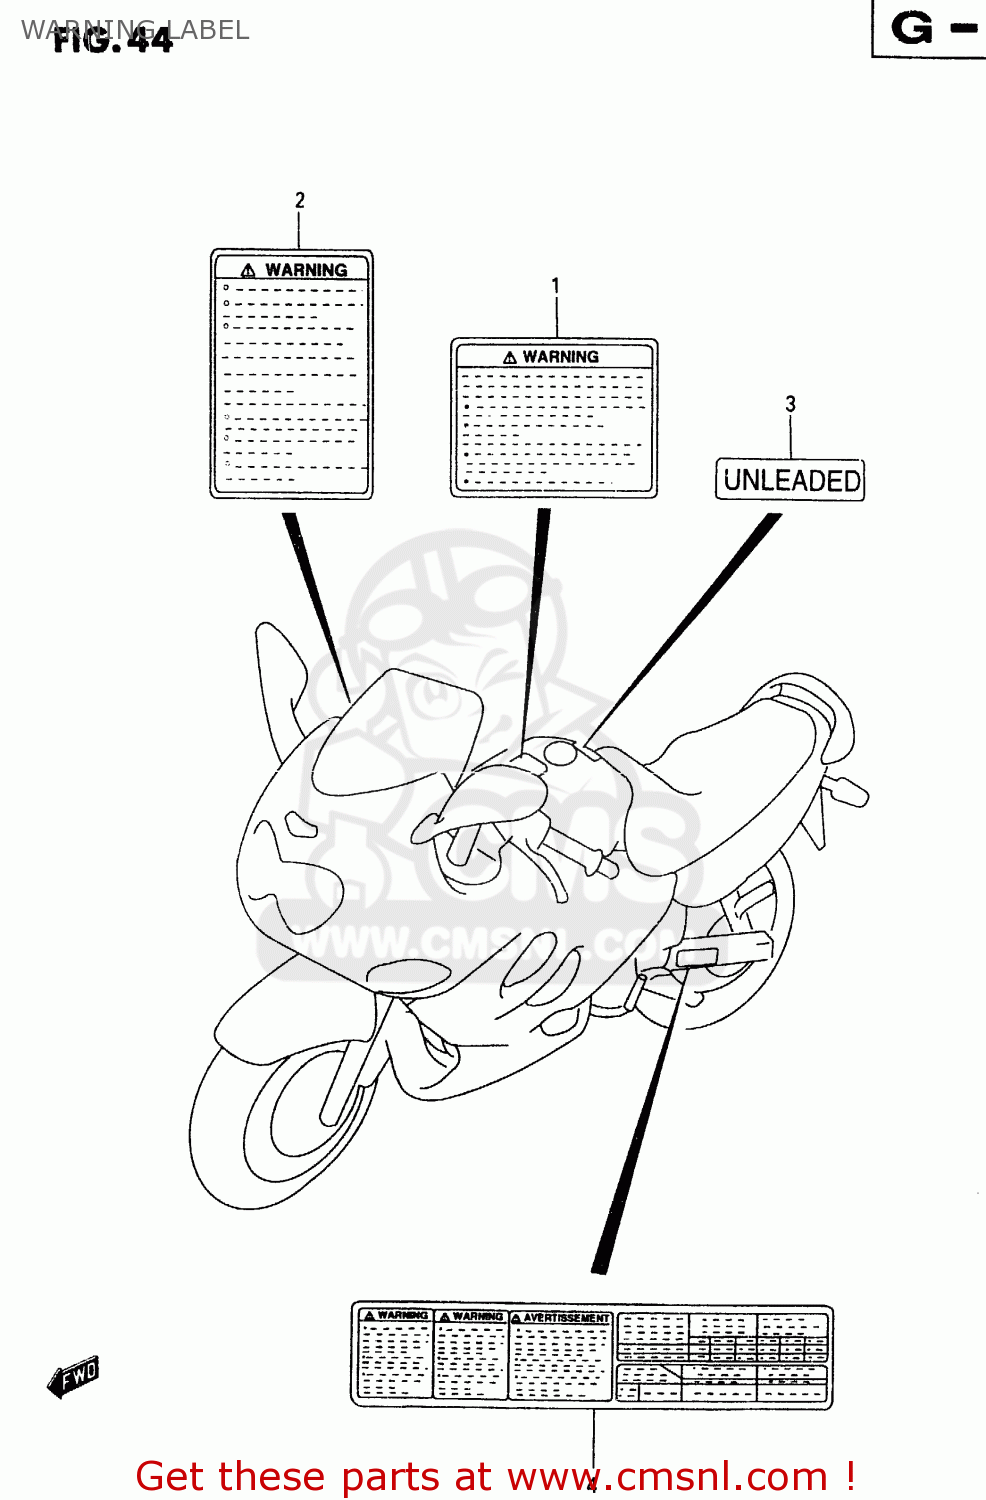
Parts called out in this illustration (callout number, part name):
1	LABEL,WARNING
2	LABEL (WARNING SCREEN)
3	LABEL,CAUTION
4	LABEL, TIRE INFORMATION
